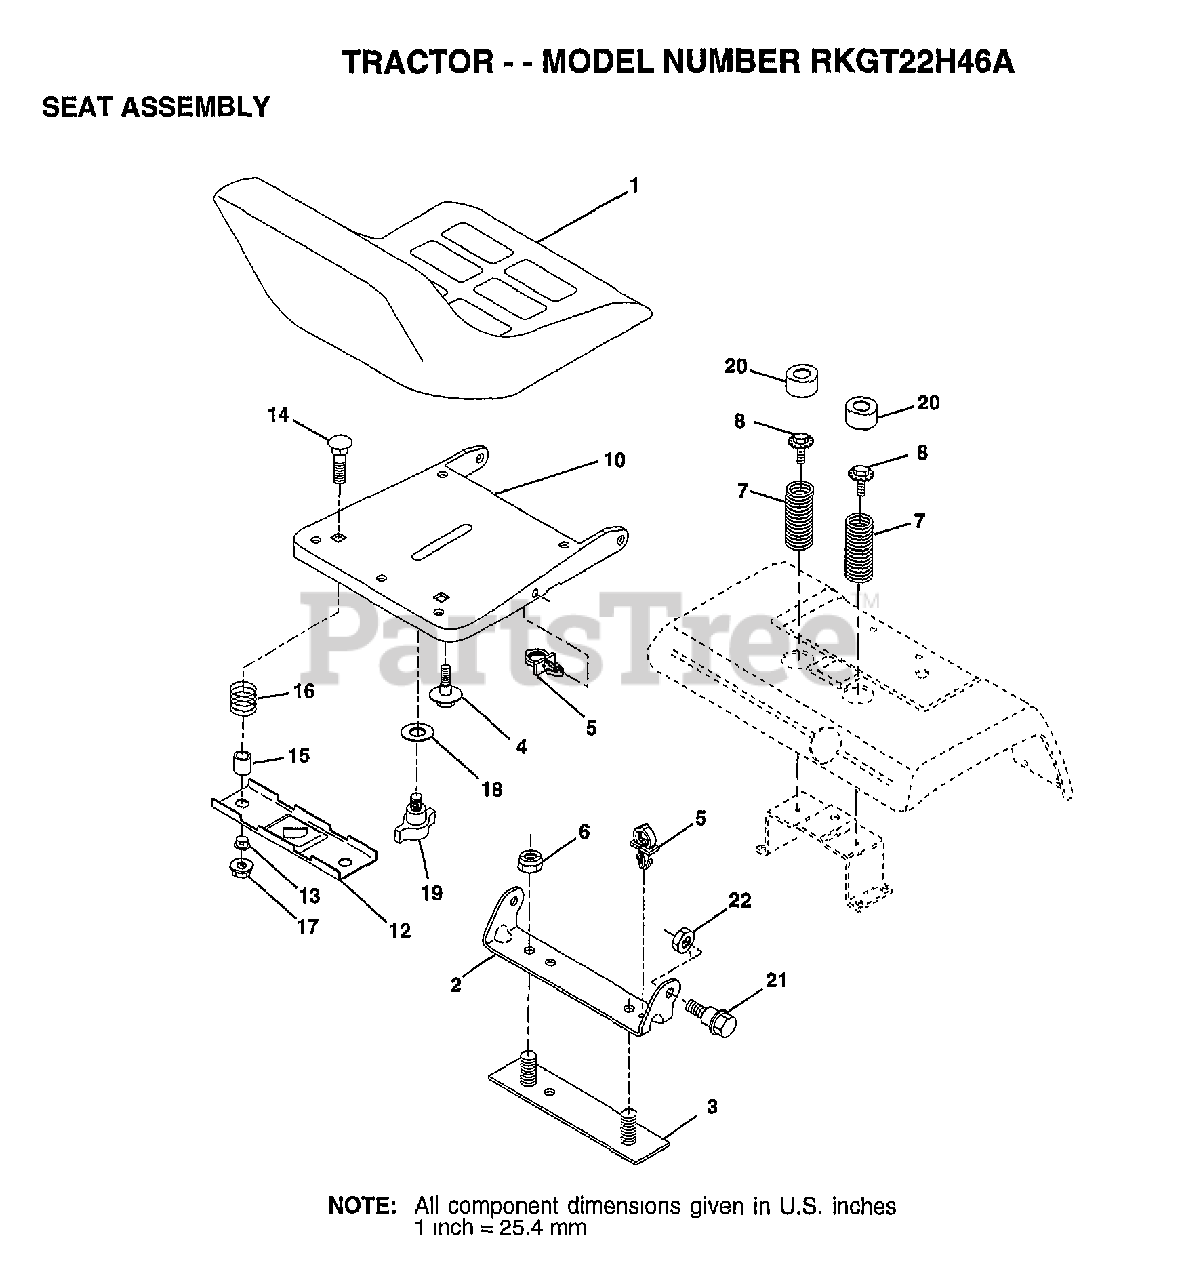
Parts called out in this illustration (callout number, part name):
2	BRACKET PVT SEAT
3	STRAP ASM FENDER
4	"BOLT,SHOULDER"
5	CLIP.PUSH-IN.HING
6	NUT
7	SPRING COMPRESSIO
8	BOLT.5/16-18.UNC
10	PAN-SEAT
12	BRKT SWITCH
13	BUSHING
14	BOLT-RD HD SQ NK
15	SPACER SPLIT
16	SPRING COMPRESSED
18	WASHER
19	KNOB.SEAT.ADJ.WINGNUT
20	CAP SPRING
21	"BOLT,SHOULDER"
22	NUT
